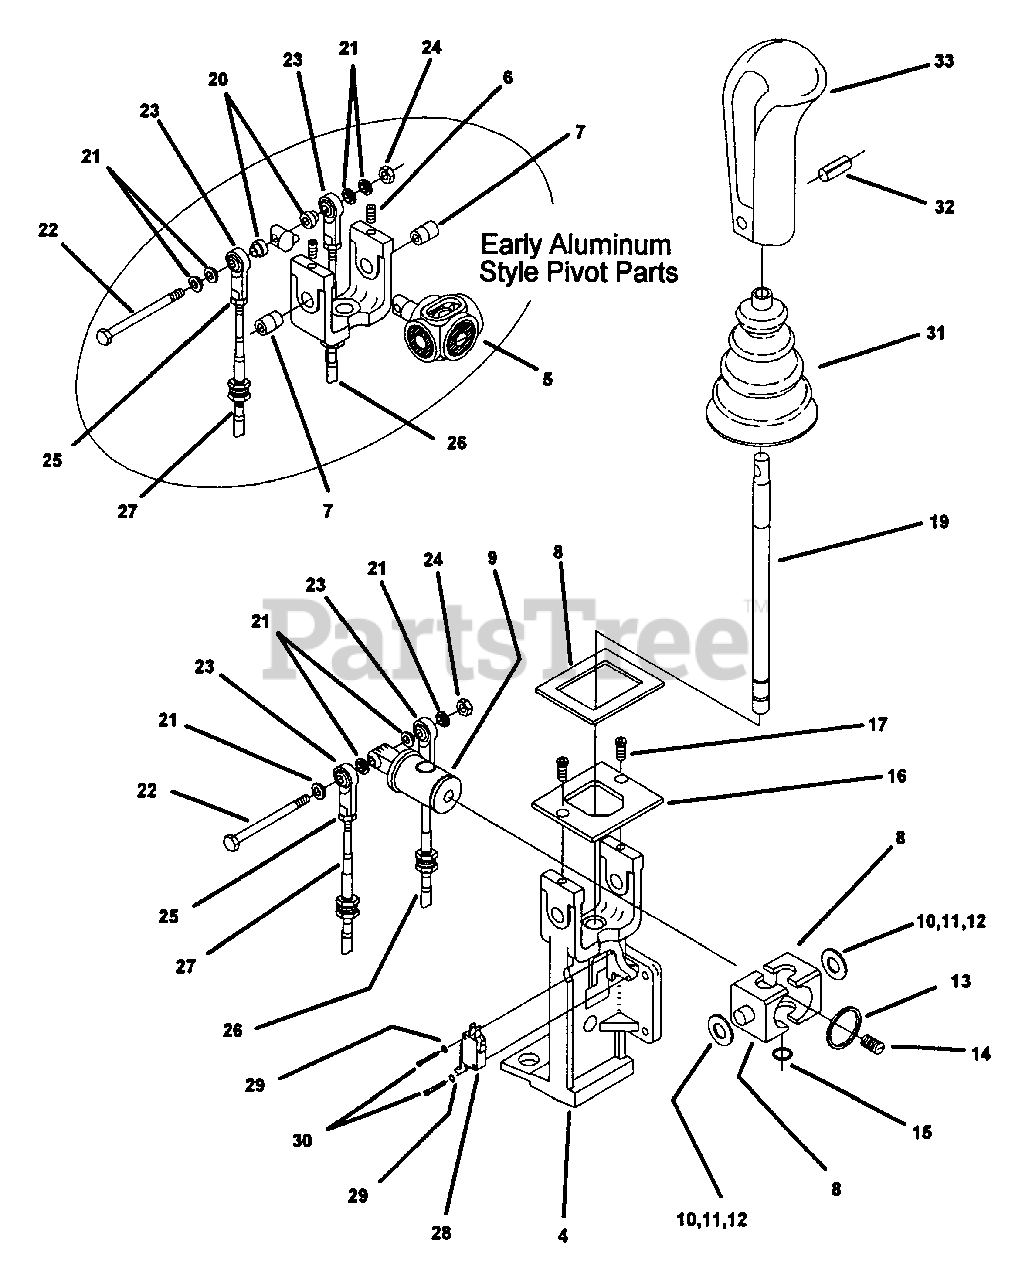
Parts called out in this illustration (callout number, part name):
4	JOYSTICK YOKE
5	PIVOT BLOCK ASSEMBLY
6	SET SCREW, 1/4-20 X 5/16 Nylock
7	TRUNNION PIN
8	PIVOT BLOCK, Delrin Plastic
9	PIVOT SHAFT, Delrin Plastic
10	SHIM WASHER, 1/2 ID x 1 OD x .005 Thick
11	SHIM WASHER, 1/2 ID x 1 OD x .010 Thick
12	SHIM WASHER, 1/2 ID x 1 OD x .020 Thick
13	SNAP RING, Spirlock
14	BALL PLUNGER, 3/8-16 X 5/8"
15	SNAP RING, 1/2"
16	TOP PLATE, Joystick
17	SCREW, 1/4-20 X 1/2", Flathead
19	JOYSTICK SHAFT
20	BUSHING, Ball Joint
21	BUSHING, Ball Joint
22	CAP SCREW, 1/4-20 X 3", Hex Head
23	BALL JOINT, 1/4-28, Female
24	NUT, 1/4-20, Nylock
25	NUT, 1/4-28,
26	PUSH-PULL CABLE, 55"
27	PUSH-PULL CABLE, 39"
28	SWITCH, SPDT, Miniature
29	LOCK WASHER, #4 Star
30	SCREW, #4-40 X 3/4"
31	BELLOWS BOOT
32	ROLL PIN, 3/16 X 1"
33	HANDLE GRIP
